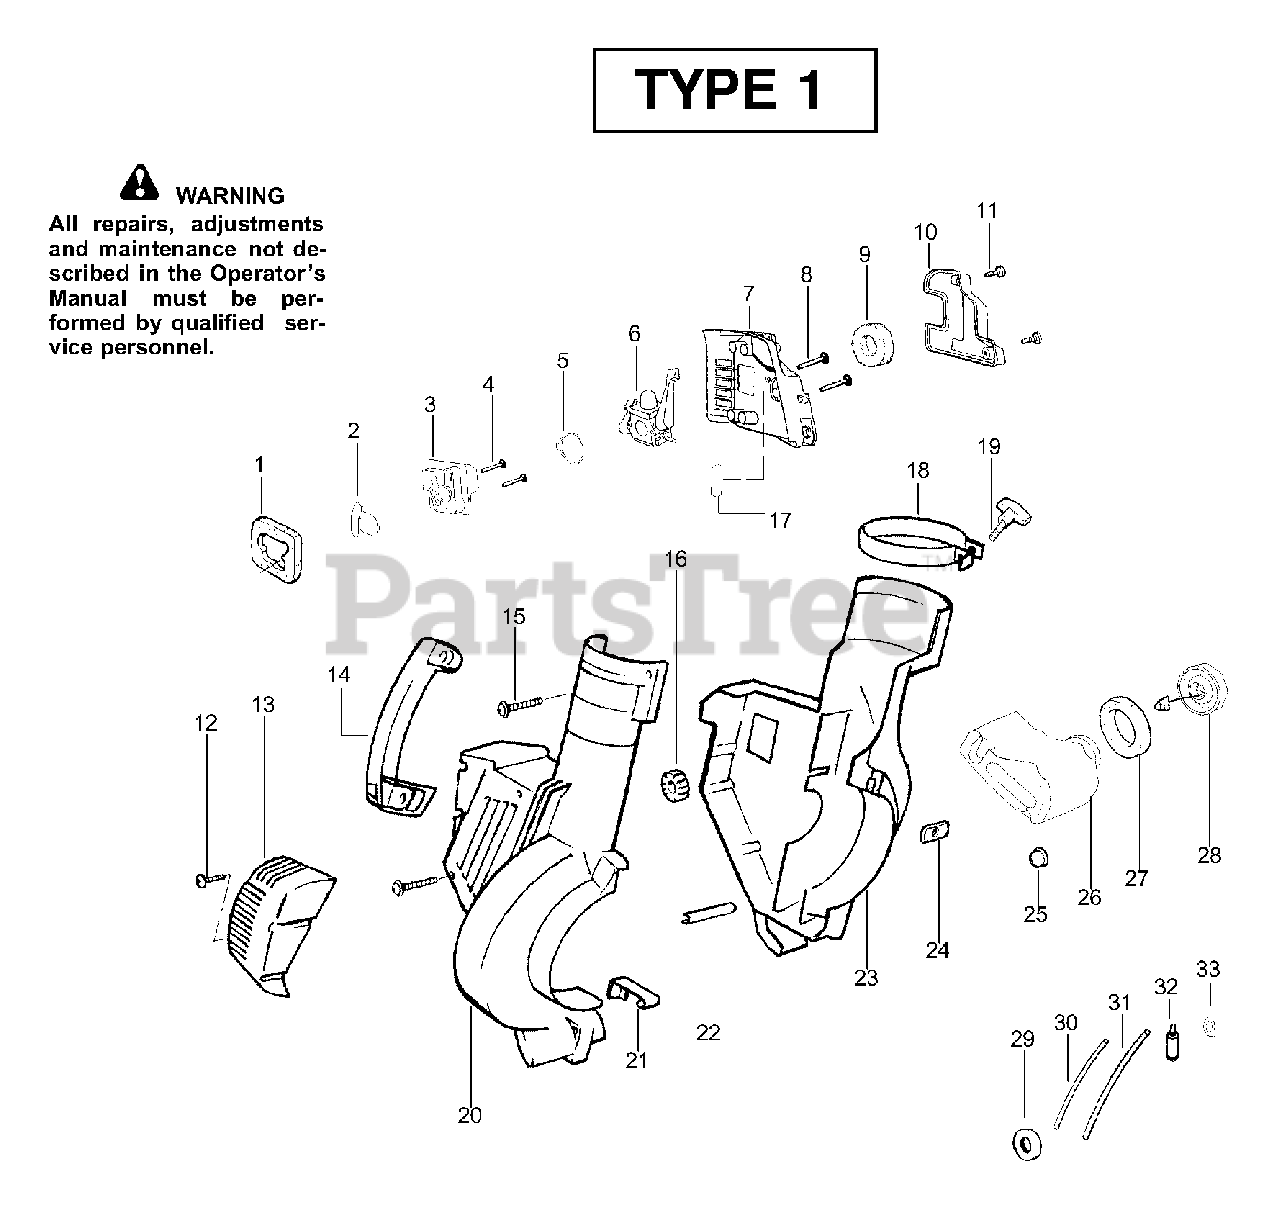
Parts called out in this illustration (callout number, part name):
1	Air Dam (kit)
2	Gasket-Adapter (kit)
3	Carburetor Adaptor
5	Gasket-Carburetor (kit)
6	Kit-Carb Ass'y (C1Q-W11)
8	Screw-Carb.
9	Filter-Air
10	Cover-Air Filter
11	Screw-Air Box Cover
13	Assy-Muffler Cover
16	Isolator
17	Foam 25.4mm (kit)
18	Clamp-Blower Tube
19	Knob-Tube Clamp
20	Housing-Right
21	Spring-Cover Latch
22	Guide-Starter Rope
23	Housing-Left
25	Isolator-Crankcase
26	Assy-Fuel Tank
27	Gasket-Fuel Tank
28	Fuel Cap w/Retainer
29	Grommet-Shroud
30	Kit-Line Carb/Purge
31	Kit-Line Tank/Purge
32	Assy-Fuel Pick-up
33	Grommet-Fuel line (kit)
